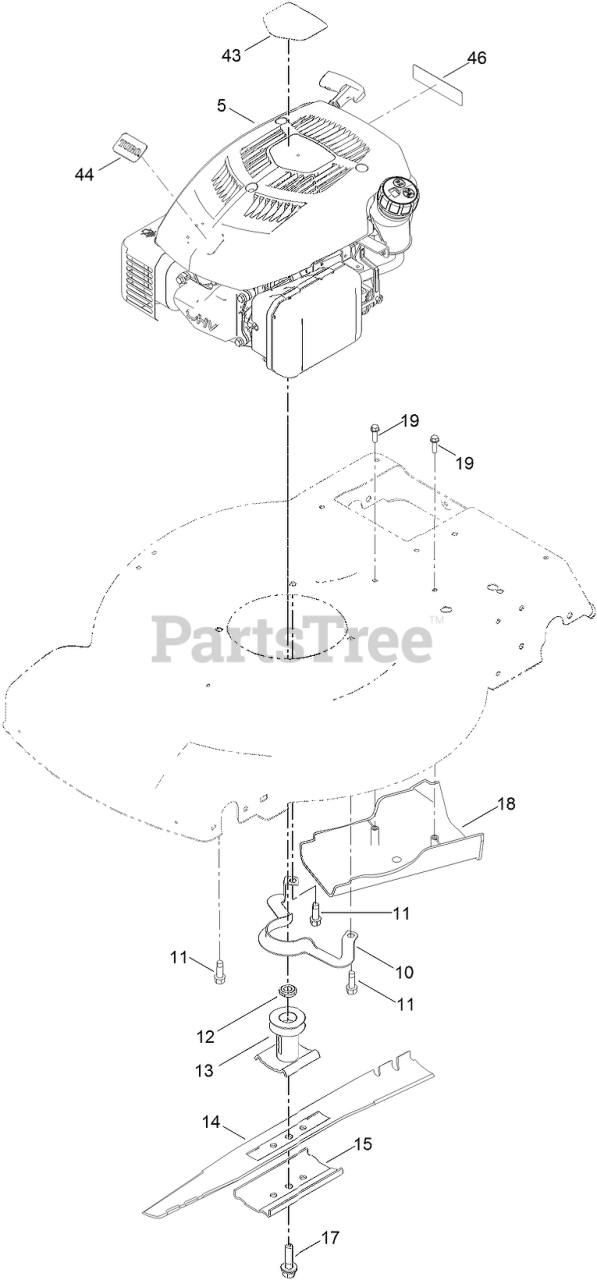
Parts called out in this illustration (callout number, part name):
5	ENGINE-1P65F-2
10	GUIDE-BELT
11	SCREW-TAPTITE
12	SPACER-DRIVER
13	DRIVER-BLADE
14	BLADE-22 INCH
15	SUPPORT-BLADE
17	BOLT-BLADE
18	COVER-BELT
19	SCREW-HWH
43	DECAL-SHROUD
46	DECAL-ARRESTER, SPARK
